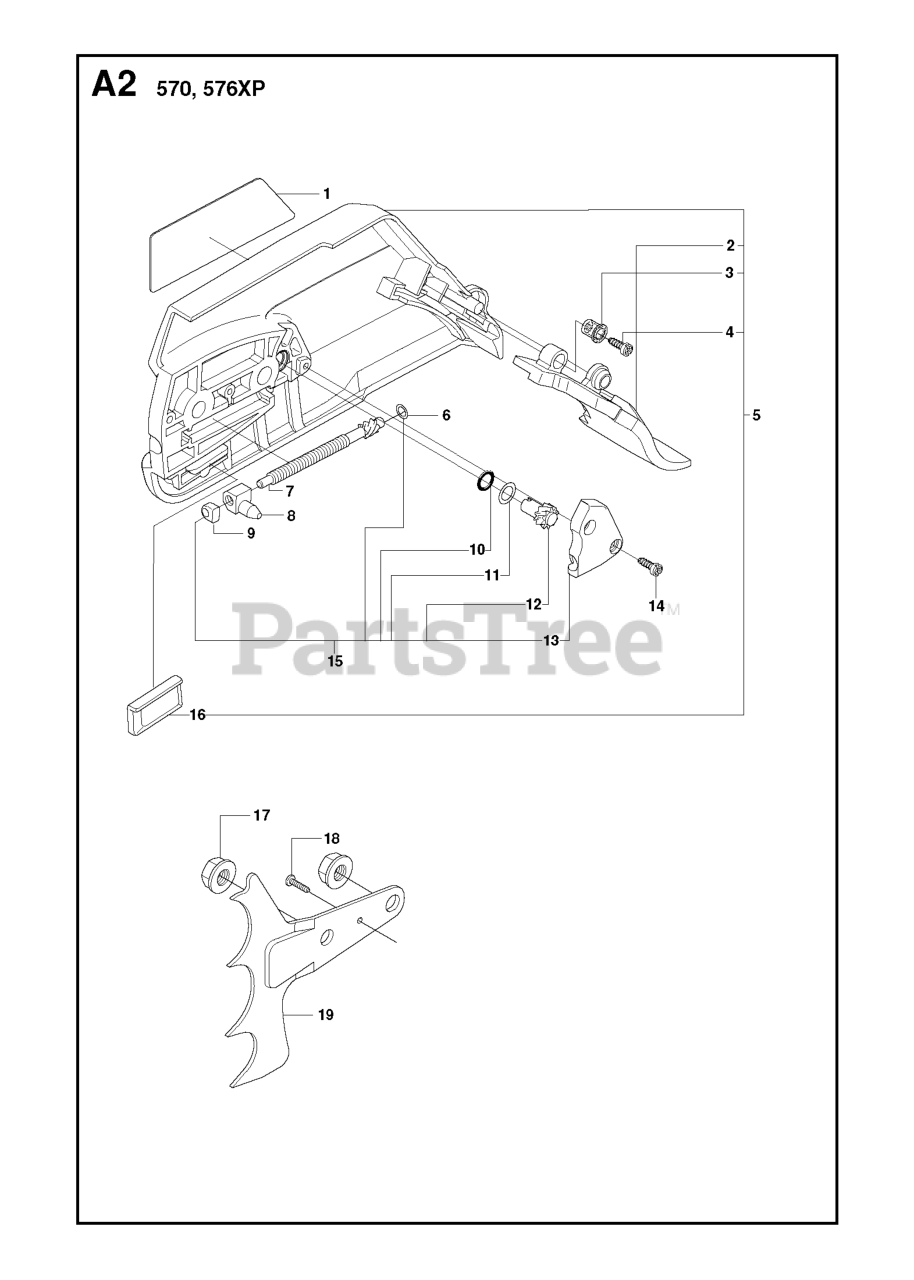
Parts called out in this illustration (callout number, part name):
5	CHAIN BRAKE COVER
5	CLUTCH COVER ASSY
7	ADJUSTER
12	RP ADJUSTER
15	KIT-CHAIN TENSIONER
16	CHAIN GUIDE
17	NUT M8 FLANGE
19	SPIKE OUTER
